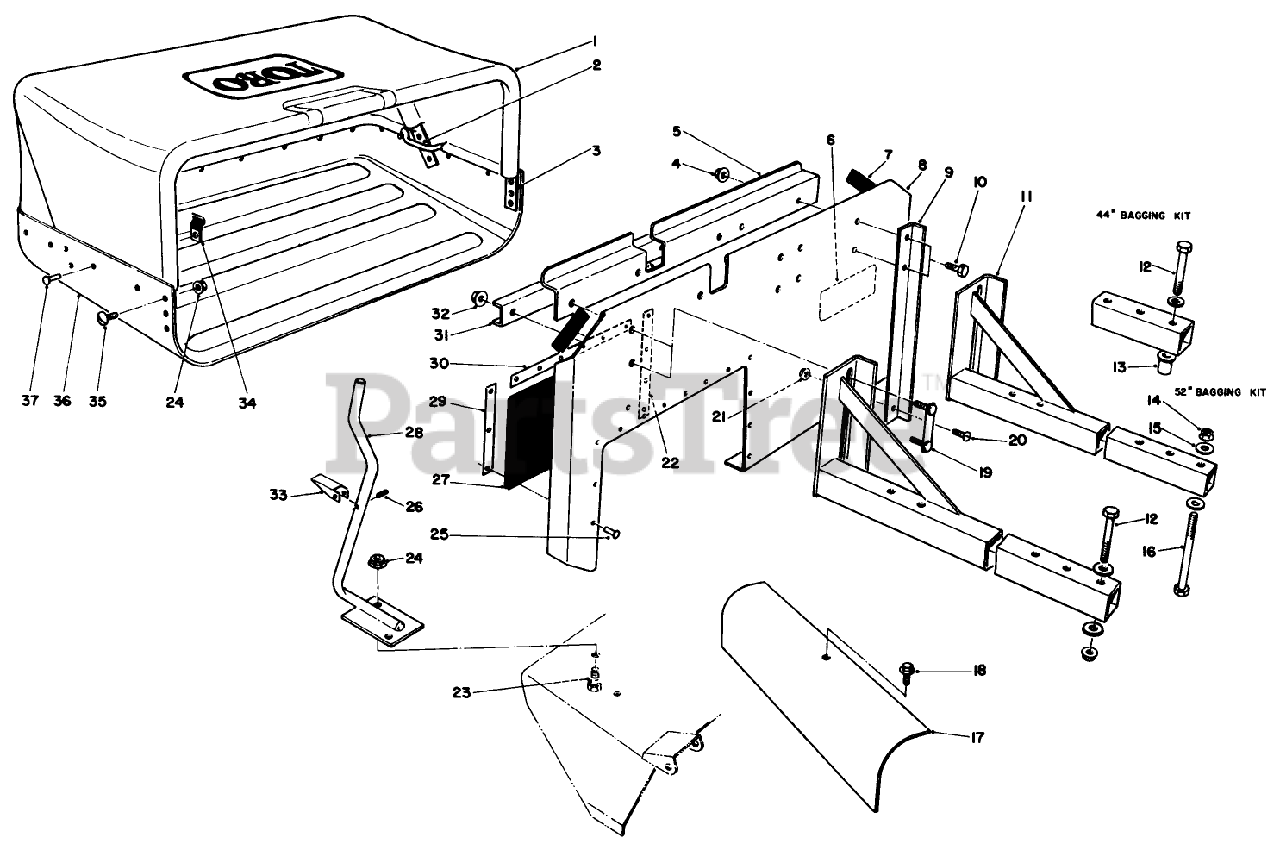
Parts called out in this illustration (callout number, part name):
2	ROD-CLOTH
4	NUT-HHF, WHIZ
6	DECAL-DANGER
7	PAD-RUBBER
10	SCREW-HH
12	SCREW-HH
13	RIVSERT
14	NUT-LOCK, NI
15	WASHER-FLAT
16	SCREW-HH
18	5/16-18X3/4 HX HD SEM
19	RETAINER-BOLT
21	NUT-LOCK, HHF
22	STRIP-SEAL, 10IN
23	SCREW-HH
24	NUT-HF
25	RIVET-POP
26	PIN-SPRING
29	STRIP
30	STRIP-SEAL, 16IN
32	NUT-LOCK, FLANGE
33	LATCH-LOCKUP
34	CLIP-HALF
35	SCREW-PPH
36	TRAY-BAG, GRASS
37	RIVET-BLIND
